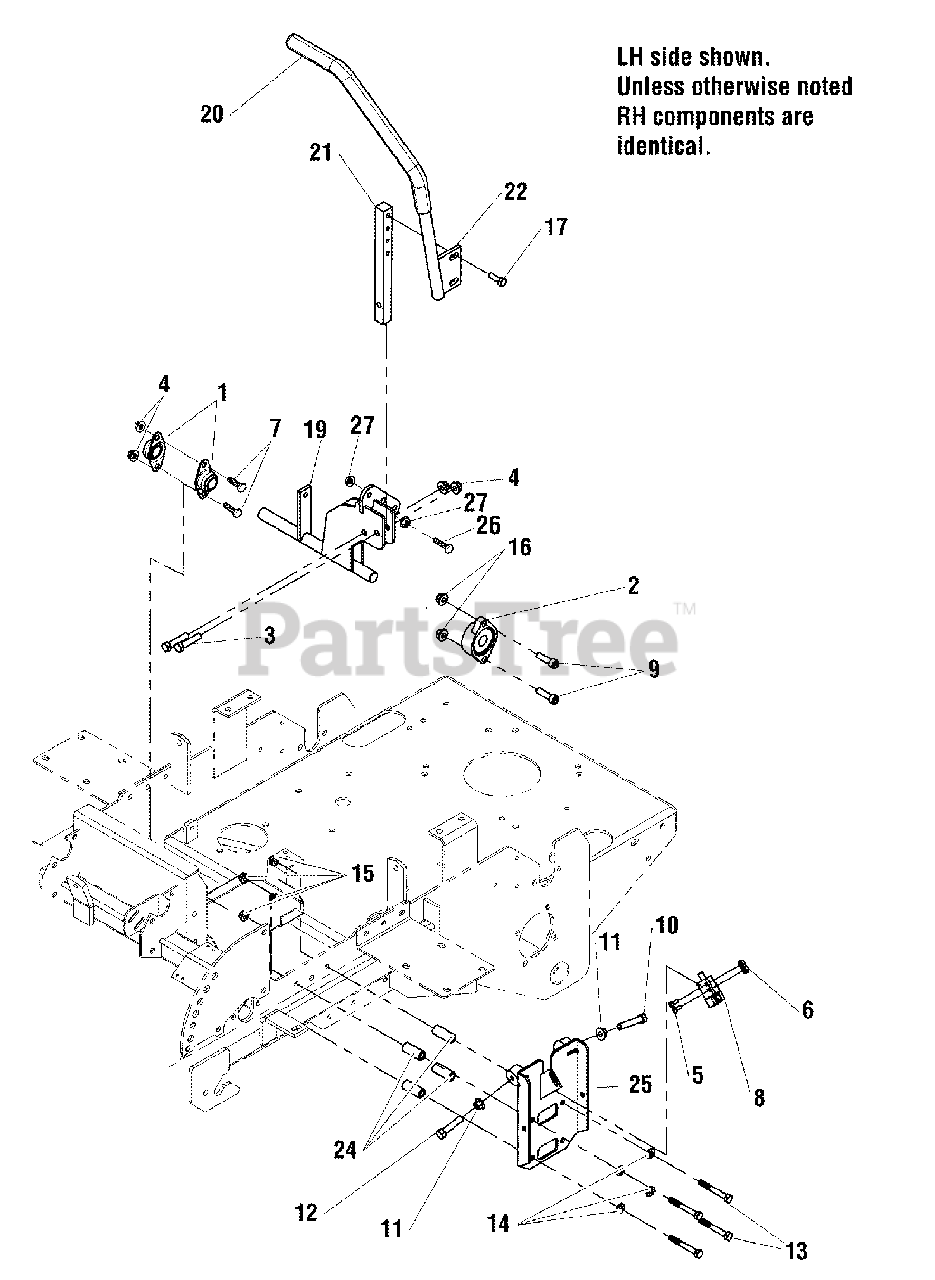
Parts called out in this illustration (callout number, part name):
1	BEARING, BRONZE FLANGE, 3/4
2	BEARING, FLANGE
3	BOLT, 3/8-16 X 1-3/4" GD5
4	NUT, 3/8-16 HEX NYLOCK FLANGE
5	SCREW, #10-24 X 1/2" ROUND PHILLIPS
6	NUT, #10-24 HEX
7	BOLT, 3/8-16 X 1" GD5 YZ
8	SWITCH, PLUNGER, N.O./N.C.
9	BOLT, 3/8-16 X 1-1/4 SHCS (SOCKET HEAD)
10	BOLT, 5/16-18 X 2" GD5 TFL
11	NUT, 5/16-18 HEX SERRATED FLANGE (LARGE)
12	BOLT, 5/16-18 X 1-3/4" GD5 TFL
13	BOLT, 5/16-18 X 2-1/2" GD5 YZ
14	WASHER, 5/16" SAE
15	NUT, 5/16-18 HEX NYLOCK FLANGE
16	NUT, 3/8-16 HEX NYLON LOCK
17	SCREW-HEX WZ LOCK FLNG 5/16-18X0.750BLK
19	WELD, CONTROL SHAFT - LH - ORG
20	GRIP, FOAM, 3/4" ID, 16" LONG
21	MOUNT, CONTROL ARM - BLK
22	WELD, HANDLE MOTION CONTROL-LH
24	SPACER, .39 X .63 X 1.50
25	WELD,PLATE,NEUTRAL
26	BOLT, 5/16-18 X 1 1/2" FLANGE
27	NUT, 5/16-18 HEX SERRATED FLANGE (LARGE)
